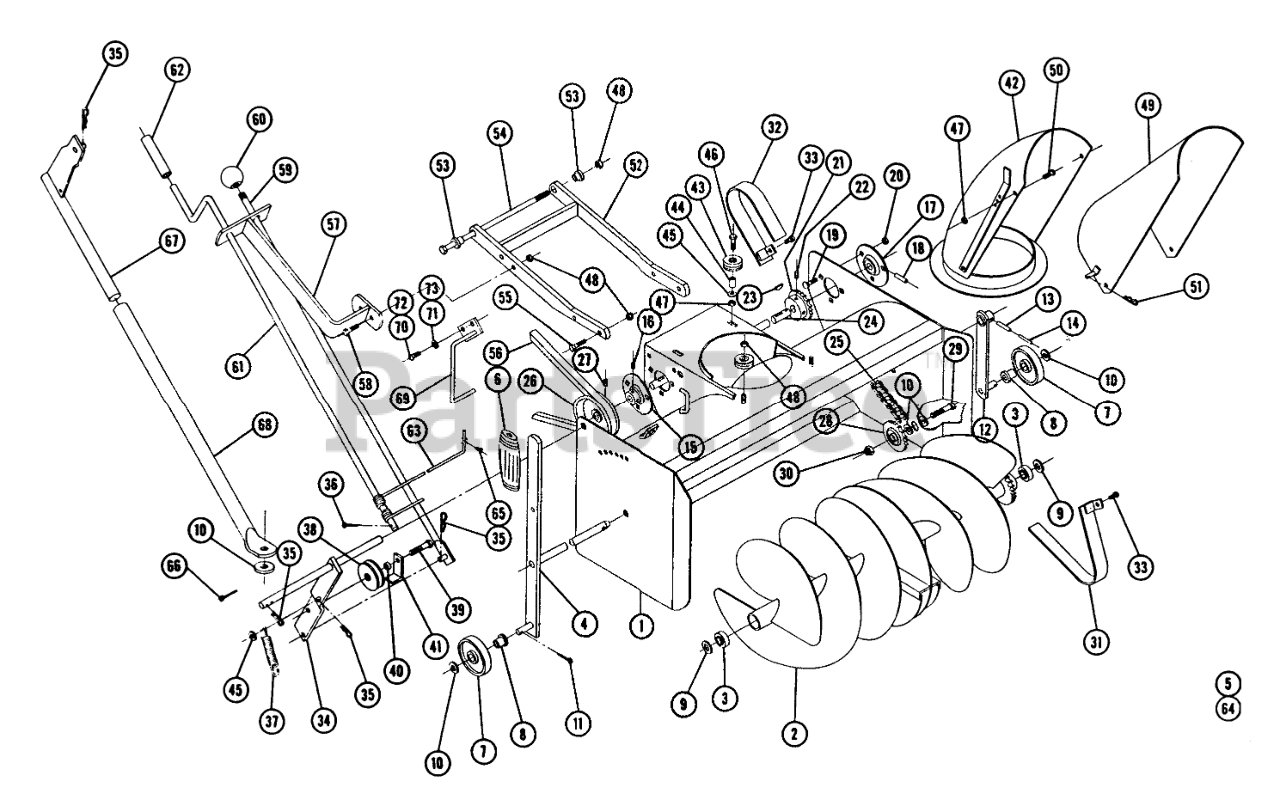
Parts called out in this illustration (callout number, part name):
1	Ass-y Wrapper
2	Auger
3	Ball
4	Auger Shaft
5	Decal
6	Grip
7	Wheel
8	Bushing
9	Washer Auger
10	Washer
11	Cotter Pin
12	Wheel Support
13	ROLL PIN 1/4 X 1-1/4
14	Roll Pin 5/32 x 1/4
15	Bearing-Flanged
16	Set Screw 5/16-18 x 5/16
17	Bearing Flanged
18	PIN-ROLL, SPIROL
19	Bolt Hex 5/16-18 x 3/4
20	Nut-Nylok
21	SPROCKET
22	Set Screw 1/4-20 x 1/4
23	Key
24	Shaft Drive
25	Chain
26	Pulley
27	Set Screw 5/16-18 x 5/16
28	Idler Sprocket
29	Bolt-1/2-13-1 3/4
30	Nut-Type TU 1/2-13 Elastic Stop
31	Ass-y Guard-Inner
32	Guard-Outer
33	SCREW
34	Ass-y Idler Bracket
35	Hairpin
36	Cotter Pin
37	Spring
38	Pulley
39	Bolt Hex 3/8-16 x 2 Nylok
40	BUSHING
41	Clip - Belt
42	S/A SHROUD R
43	Roller
44	SPACER
45	Washer
46	Bolt 1/4 20 x 1 1/4
47	Nut-Nylok
49	Deflector
50	Bolt Rd. Hd. 1/4-20 x 1/2
51	Hairpin
52	Ass-y Mounting Frame
53	Spacer
54	Bolt-Hex. 3/8-16 x 8 1/2
55	Bolt 3/8-16 x 7/8
56	V-BELT
57	Bracket-Control Guide & Support
58	Bolt 3/8-16 x 1
59	Ass-y Rod-Clutch
60	Knob
61	Crank
62	Tube
63	Cable
64	Decal-Caution
65	Screw-Rd. Hd. Mach. #6-32 x 1/4
66	Cotter Pin 3/16 x 1
67	Lid Rod
68	Lift Tube
69	Ass-y. Belt Stop
70	Bolt Round Head 5/16-24 x 3/4
71	Lockwasher
72	Screw 1/8-16 x 3/4
73	Lockwasher
